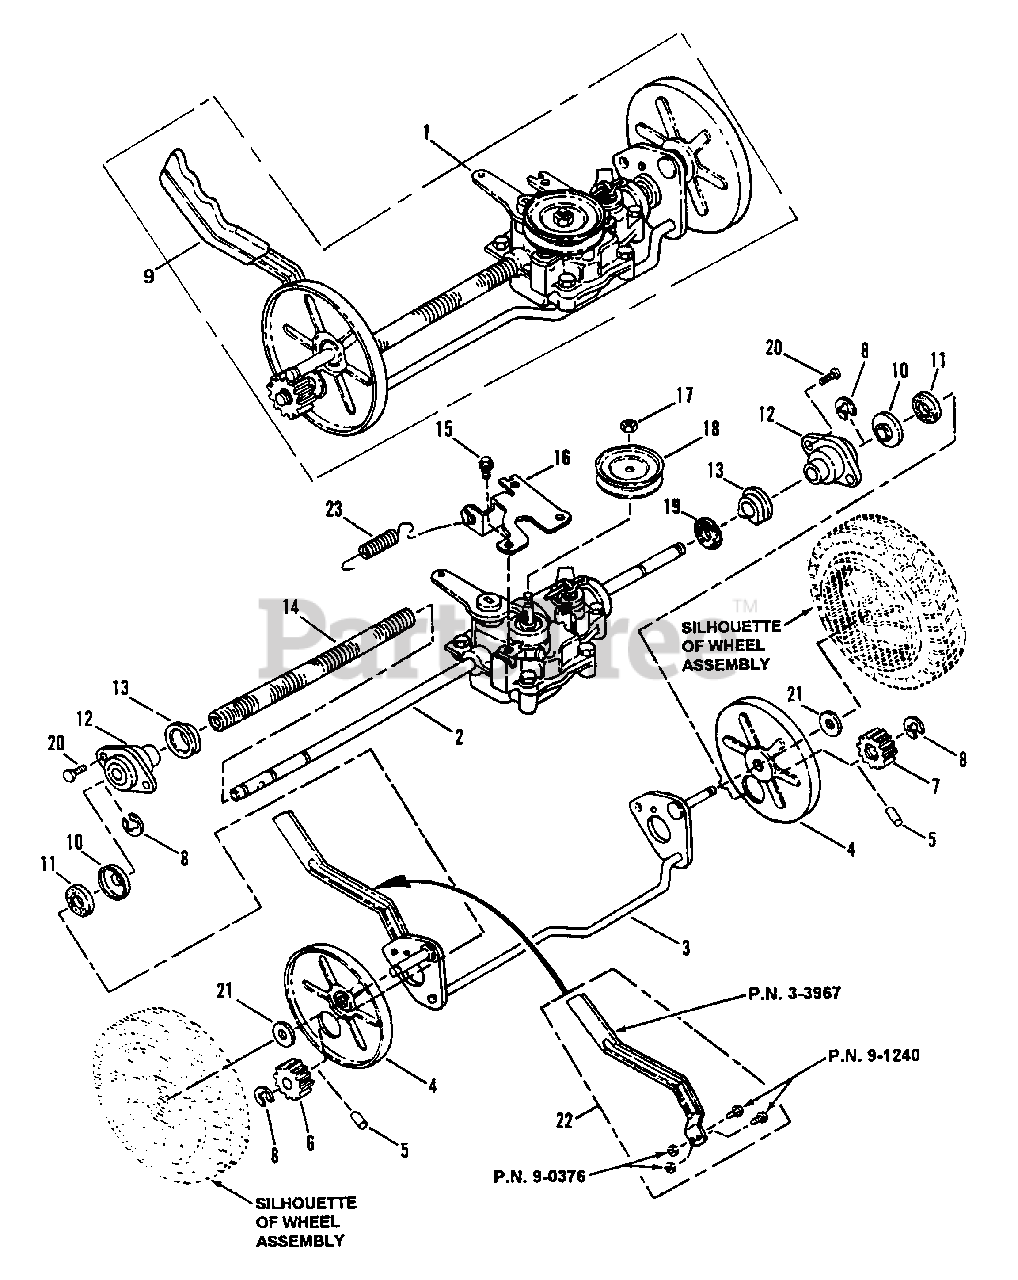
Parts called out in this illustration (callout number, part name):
1	AXLE/TRANSMISSION ASSEMBLY
2	ASSEMBLY, Transmission
3	ASSEMBLY, Rear Axle Weldment
4	SHIELD, Dust
5	PIN, Pawl, 3/16 O.D.
6	PINION, Right Hand Drive
7	PINION, Left Hand Drive
8	RING, External Retaining
9	GRIP, Height Adjust Lever
10	RETAINER, Pinion Seal
11	SEAL, Pinion (Felt)
12	ASSEMBLY, Bearing Carrier
13	BUSHING, Rear Axle
14	TUBING, 5/8" I.D., Convoluted
15	SCREW, 5/16-18 x 5/8" Hex Washer Head, Self-Tapping
16	BRACKET, Transmission
17	NUT, M10-1.50 Hex Nyloc
18	PULLEY, Transmission
19	WASHER, Felt
20	SCREW, 1/4-20 x 3/8" Hex Washer Head, Self-Tapping
21	WASHER, 17/32 I.D. x 1-1/2" O.D.
22	KIT, Height Adjusting Lever
23	SPRING, Transmission Extension (Short)
